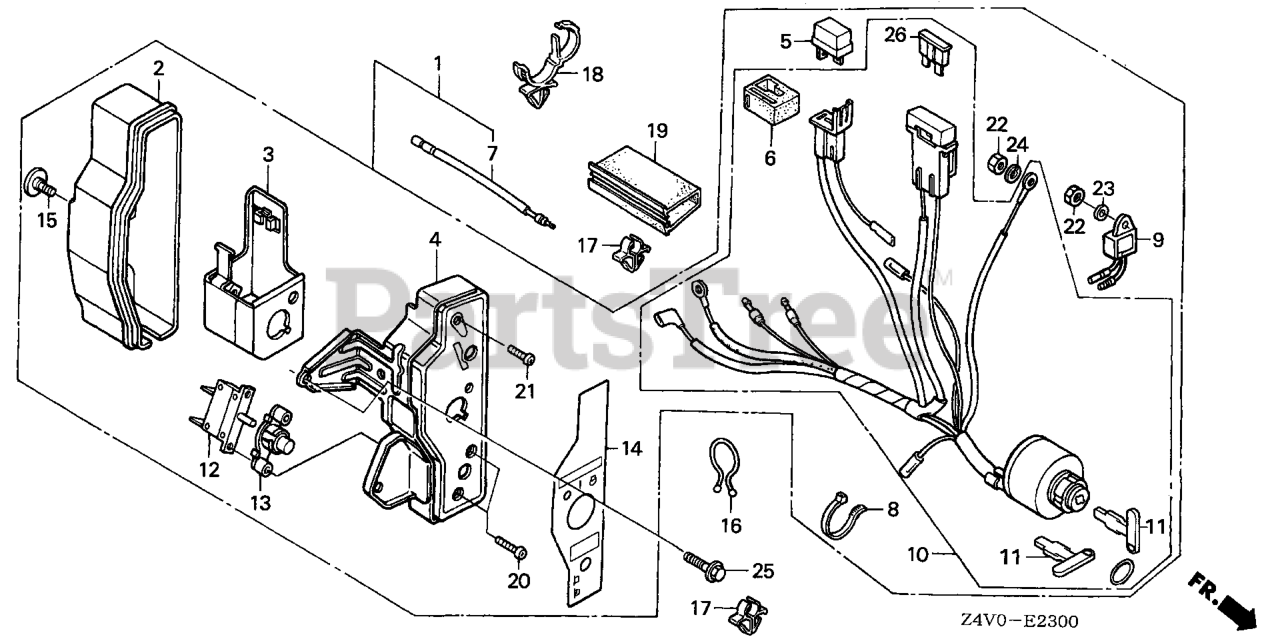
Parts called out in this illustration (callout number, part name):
1	BOX ASSY., CONTROL *R280* (POWER RED)
1	BOX ASSY., CONTROL *NH1* (BLACK)
2	CASE, CONTROL
3	BRACKET, CASE MOUNTING
4	PANEL, CONTROL *NH1* (BLACK)
4	PANEL, CONTROL *R280* (POWER RED)
7	SUB-WIRE HARNESS
8	BAND
9	ALERT UNIT, OIL
10	SWITCH ASSY., COMBINATION
11	KEY
14	MARK, CONTROL BOX (EXP)
15	SCREW, SPECIAL (6X12)
16	CLIP, PURSE LOCK
17	CLIP, CORD
18	STRAP, WIRE HARNESS (25MM) (BLACK)
19	TUBE, FASTENER (30)
21	SCREW, PAN (4X12)
22	NUT, HEX. (4MM)
23	WASHER, PLAIN (4MM)
24	WASHER, SPRING (4MM)
25	BOLT, FLANGE (6X10)
26	FUSE, BLADE (25A)
